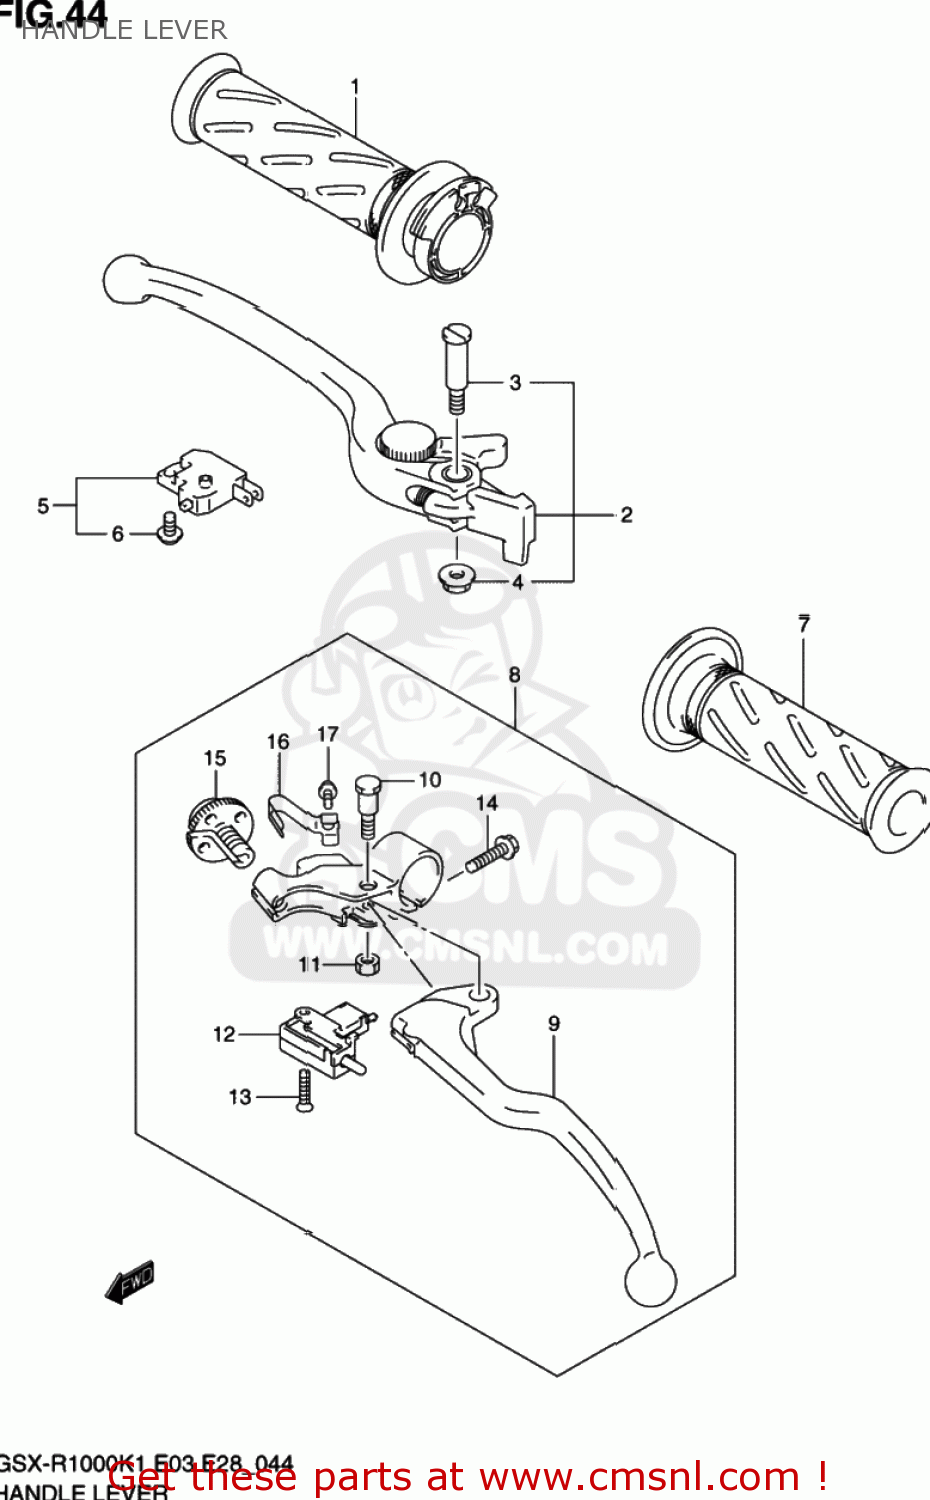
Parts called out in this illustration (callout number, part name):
1	GRIP,THROTTLE
2	LEVER ASSY,BRAKE
3	BOLT,LEVER PIVOT
4	NUT
5	SWITCH ASSEMBLY,STOP
6	SCREW
7	GRIP,LEFT
8	LEVER ASSY,CLU
9	LEVER,CLUTCH
10	BOLT,LEVER PIVOT
11	NUT
12	SWITCH,CLUTCH
13	SCREW
14	SCREW
15	NUT,CABLE ADJUSTER
16	SPRING,ADJUST
17	SCREW,SPRING
